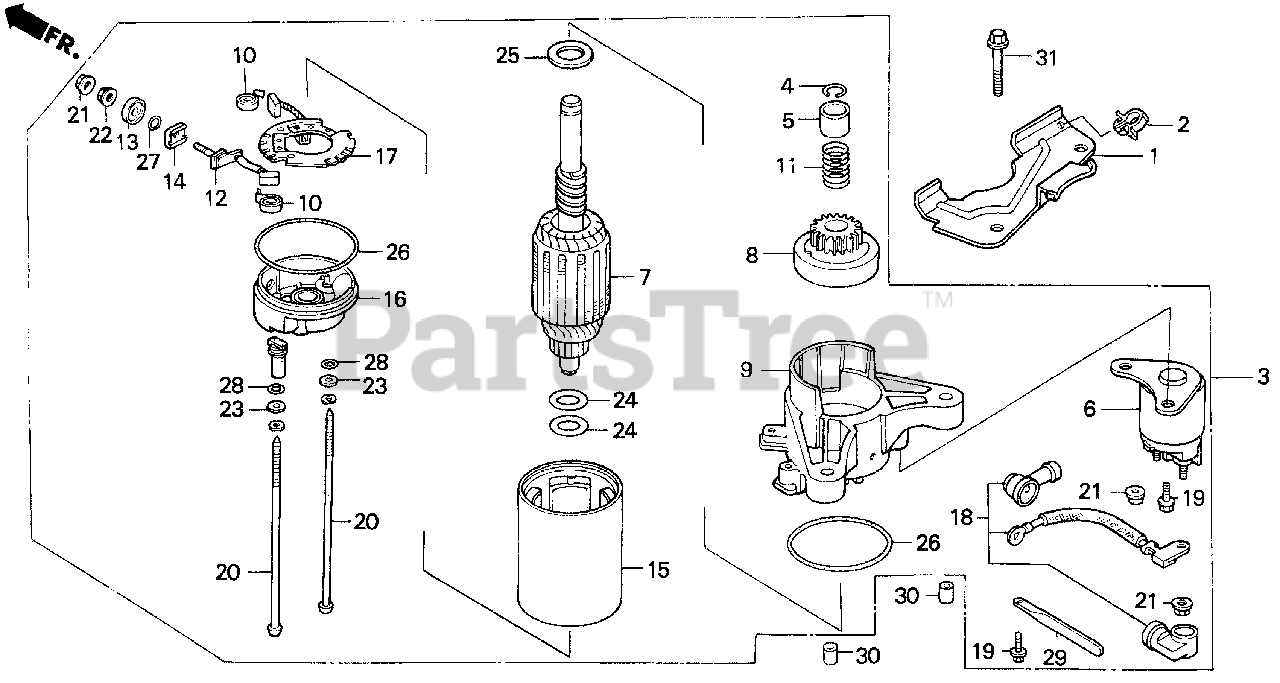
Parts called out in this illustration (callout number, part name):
1	PLATE, SIDE
2	CLIP, IGNITION WIRE (8MM)
3	MOTOR ASSY., STARTER
4	RING, SNAP
5	COLLAR, CLUTCH
6	CONTACTOR ASSY.
7	ARMATURE
8	CLUTCH, OVERRUNNING
9	HOUSING, DRIVE SIDE
10	SPRING, BRUSH
11	SPRING
12	BRUSH
13	BUSHING, INSULATION
14	BUSHING, INSULATION
15	YOKE
16	FRAME, STARTER END
17	PLATE, BRUSH HOLDER
18	WIRE, WATER COVER
19	BOLT
20	BOLT, THROUGH
21	NUT
22	NUT
23	WASHER, STEEL PLATE
24	WASHER
25	WASHER
26	O-RING
27	O-RING
28	O-RING
29	CLAMP, WIRE
30	PIN A, DOWEL (10X16)
31	BOLT, FLANGE (8X35)
32	CLIP A, BRAKE PIPE
